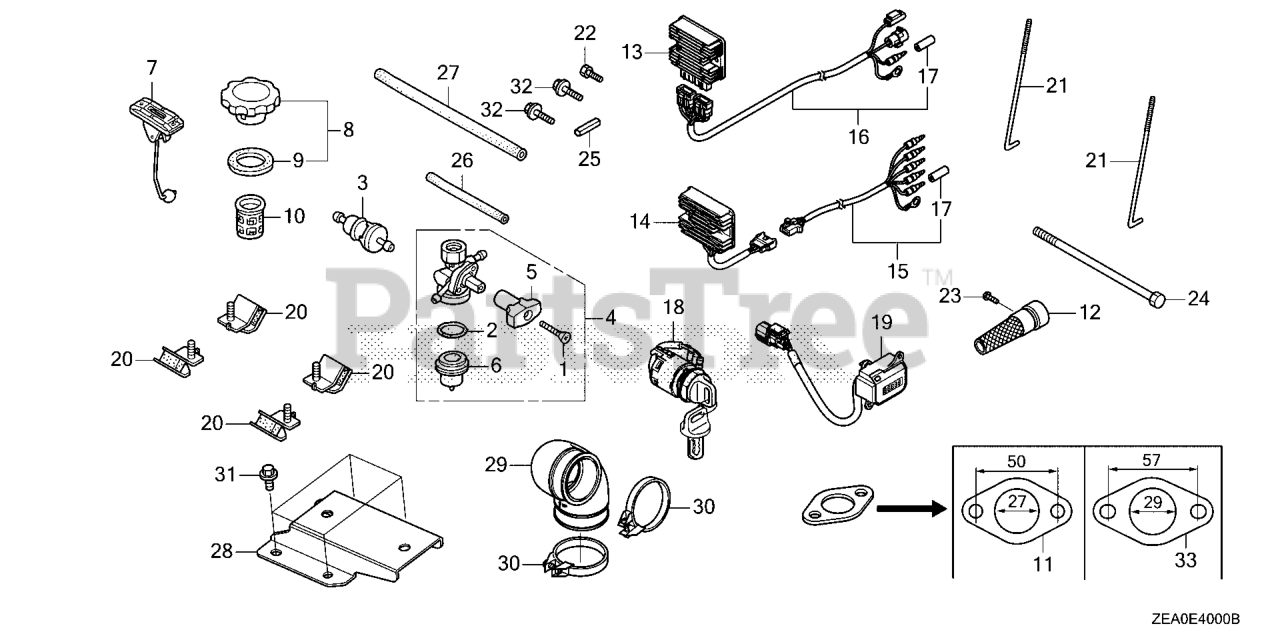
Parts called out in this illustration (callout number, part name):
11	GASKET, EX. PIPE
14	RECTIFIER ASSY., REGULATOR (17A)
15	SUB-WIRE HARNESS ASSY.
17	PLUG, CONNECTOR (OUTER) (ENGINE NO.)
25	KEY (6.3X6.3X43)
